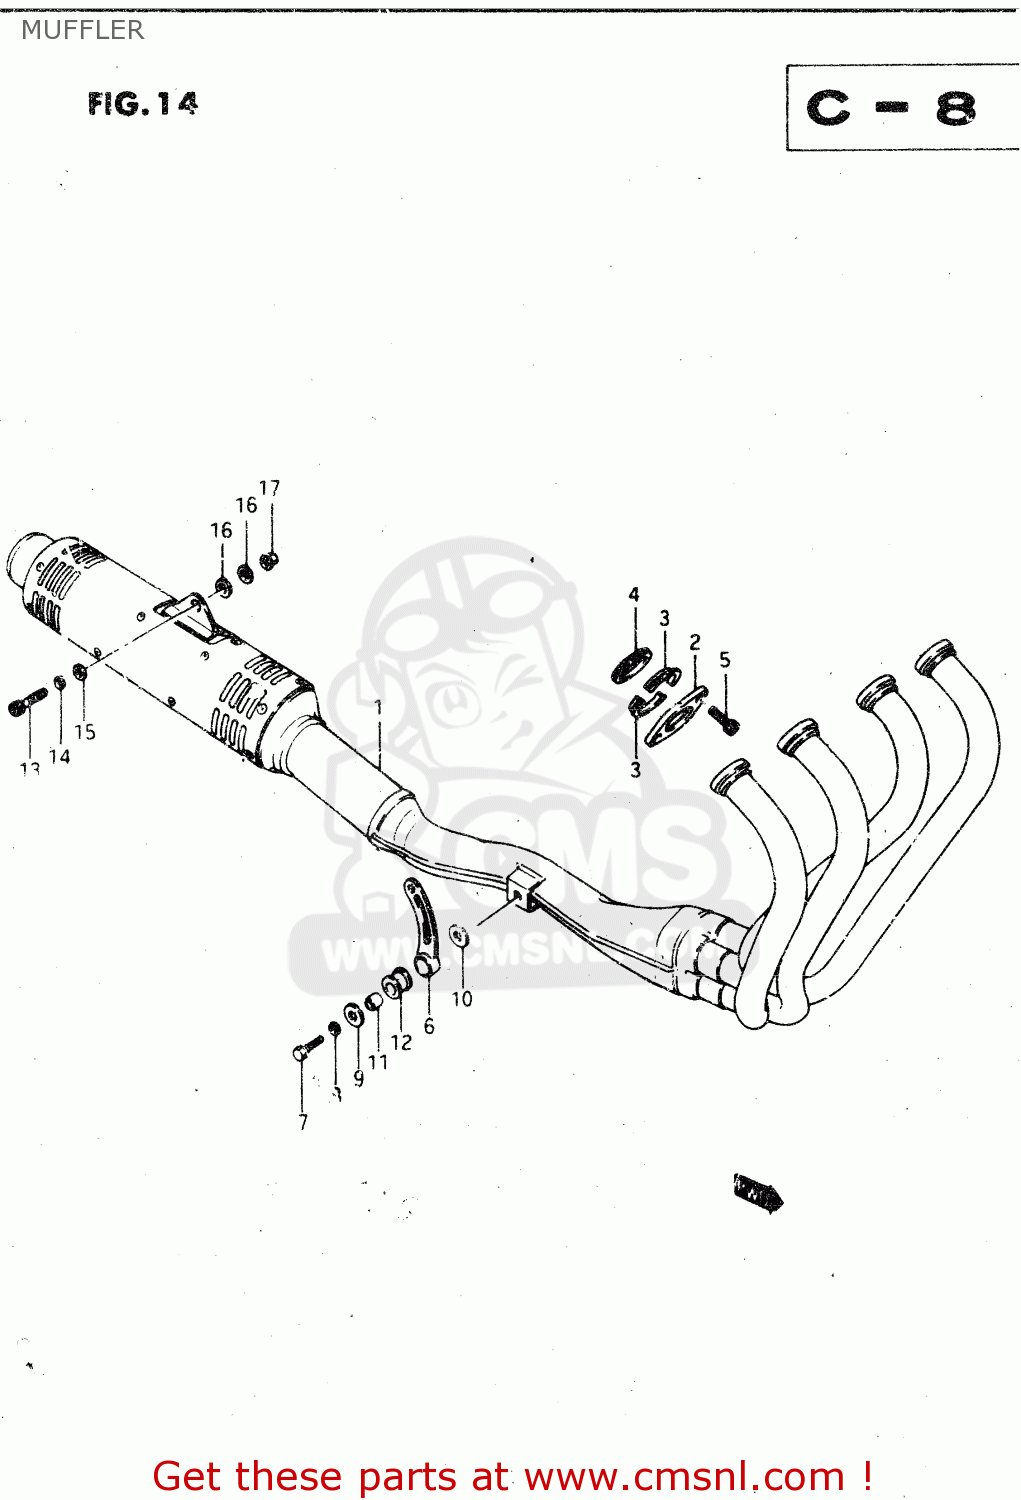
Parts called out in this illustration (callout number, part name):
1	MUFFLER ASSY
2	CLAMP,EXHAUST PIPE
3	PLATE,EXHAUST PIPE
4	GASKET,EXHAUST PIPE (NAS)
5	BOLT
6	DAMPER,MUFFLER SUPPORT
7	BOLT 8X35
8	WASHER
9	WASHER
10	WASHER (8.5X20X1.6)
11	SPACER (8.6X12X17.5)
12	CUSHION
13	BOLT
14	WASHER,LOCK
15	WASHER 10MM
16	WASHER
17	NUT
